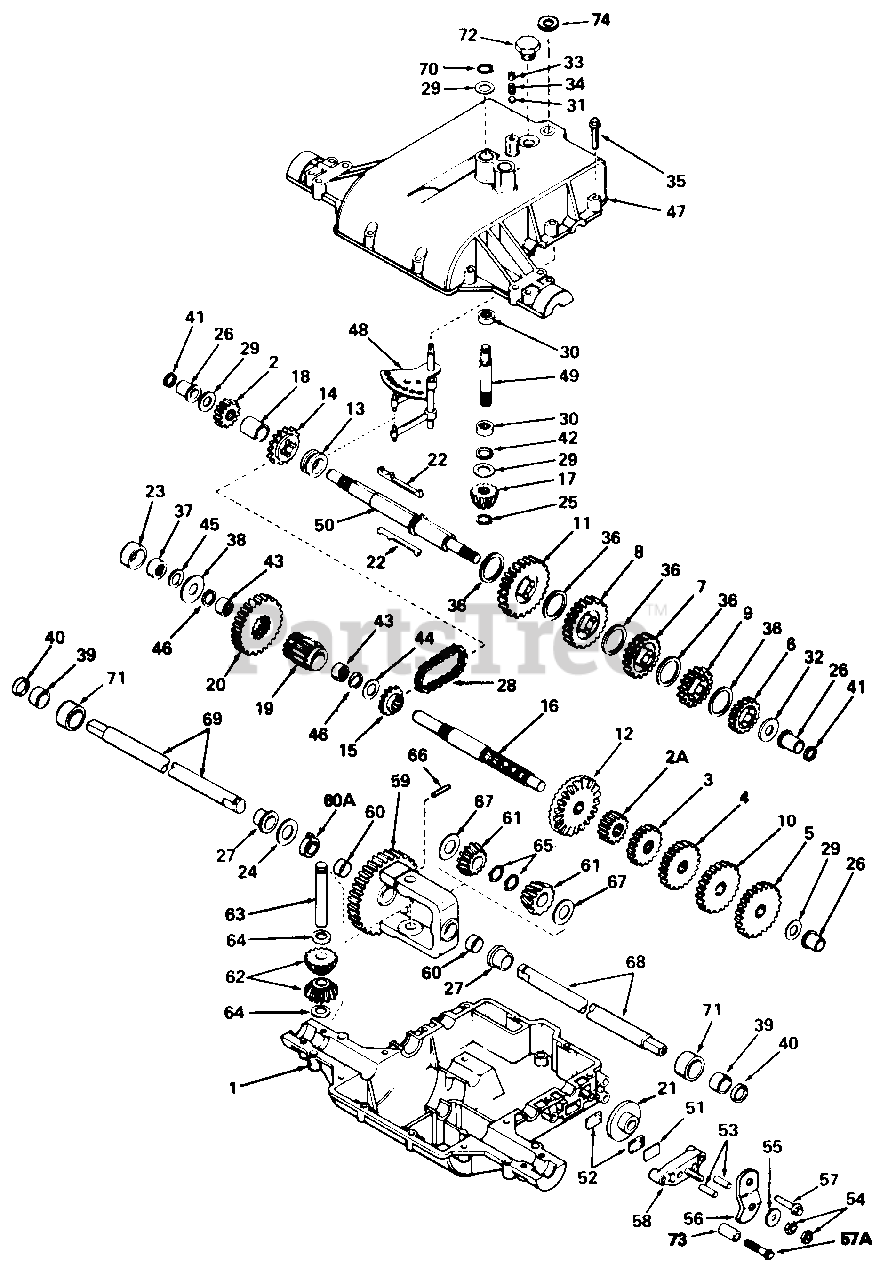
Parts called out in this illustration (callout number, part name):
1	Case, Transaxle
2	Gear, Spur (15 Teeth)
2A	Gear, Spur (12 Teeth)
3	Gear, Spur (15 Teeth)
4	Gear, Spur (20 Teeth)
5	Gear, Spur (30 Teeth)
6	Gear, Spur (20 Teeth)
7	Gear, Spur (30 Teeth)
8	Gear, Spur (35 Teeth)
9	Gear, Spur (25 Teeth)
10	Gear, Spur (25 Teeth)
11	Gear, Spur (37 Teeth)
12	Gear. Bevel (42 Teeth)
13	Collar, Shift
14	Sprocket (18 Teeth)
15	Sprocket (9 Teeth)
16	Shaft, Counter
17	Bevel Pinion, Input
18	Spacer
19	Pinion, Output
20	Gear, Output
21	Disc, Brake
22	Key
23	Spacer
24	Washer
25	Ring, Retaining
26	Bushing, Flanged
27	Bushing, Flanged
28	Chain, Roller (No. 41 Chain, 24 Links)
29	Washer, Thrust
30	Bearing, Needle
31	Ball, Steel
32	Washer, Thrust
33	Screw, Set, 3/8-16 x 3/8
34	Spring
35	Screw, Hex Hd. Thread Forming, 1/4-20 x 1-1/4
36	Washer, Thrust
37	Bearing, Needle
38	Washer, Flat
39	Bearing, Needle
40	Seal, Oil
41	Ring, Square Cut
42	Ring, Square Cut
43	Bearing, Needle
44	Washer, Flat
45	Ring, Square Cut
46	Ring, Square Cut
47	Cover, Transaxle
48	Rod and Fork Ass'y., Shift
49	Shaft, Input
50	Shaft, Brake
51	Plate, Brake Pad
52	Pad, Brake
53	Pin, Dowel
54	Lock Nut, 5/16-24
55	Washer, Flat
56	Lever, Brake
57	Screw, Hex Hd. Thread Forming, 1/4-20 x 1-1/4
57A	Screw, Hex Hd. Thread Forming, 1/4-20 x 2-1/4
58	Holder, Brake Pad
59	Gear Ass'y., Differential
60	Bushing
60A	Bushing
61	Gear, Bevel
62	Pinion, Bevel
63	Pin Drive
64	Washer, Thrust
65	Ring, Retaining
66	Pin, Roll
67	Washer, Thrust
68	Axle (14-718" Long)
69	Axle (13" Long)
70	Ring, Retaining
71	Spacer
73	Spacer
74	Washer
